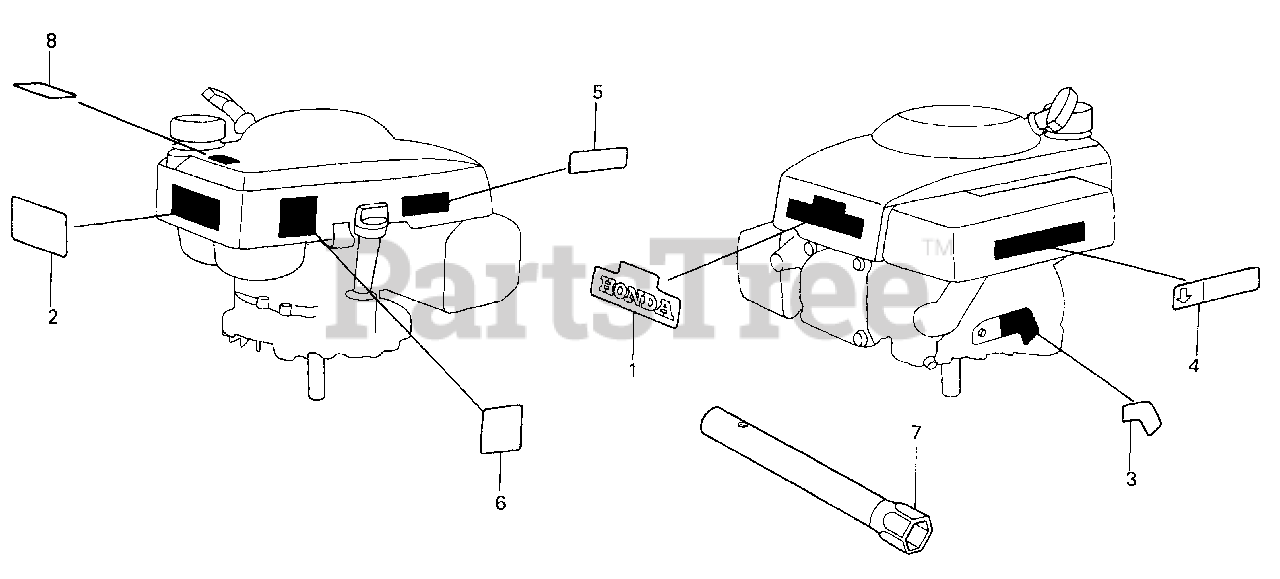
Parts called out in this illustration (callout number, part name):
1	MARK, TOP COVER
2	MARK, CAUTION (USA)
3	MARK, CONTROL
4	MARK, AIR CLEANER CAUTION
5	MARK, BRAKE CAUTION
6	MARK, OIL CAUTION
7	WRENCH, BOX (P21)
